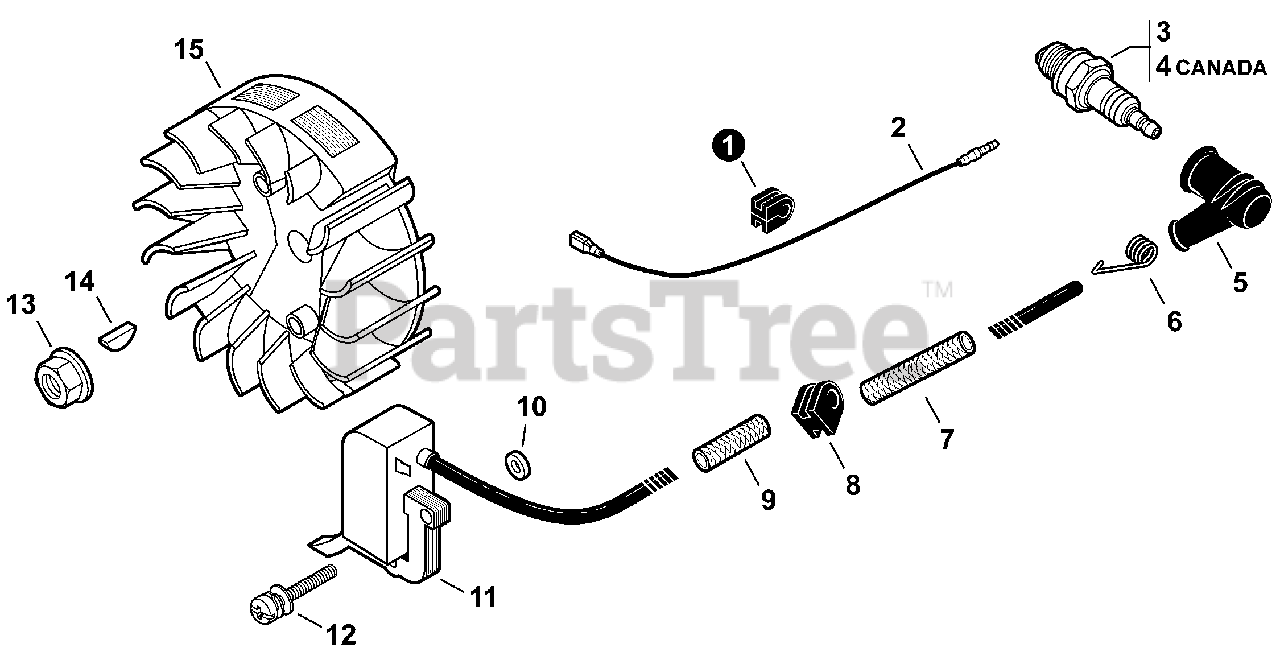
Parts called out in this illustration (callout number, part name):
2	LEAD - IGNITION
3	SPARK PLUG - BPM8Y
4	SPARK PLUG - BPMR8Y
5	CAP, SPARK PLUG
6	TERMINAL, SPARK PLUG
7	TUBE, INSULATOR 7×8.6×50
9	TUBE, INSULATOR 7×8.6×30
10	WASHER 5.2×12×3
11	COIL, IGNITION
12	SCREW 5×18
13	NUT, FLANGE M8
14	KEY, WOODRUFF
15	FLYWHEEL
